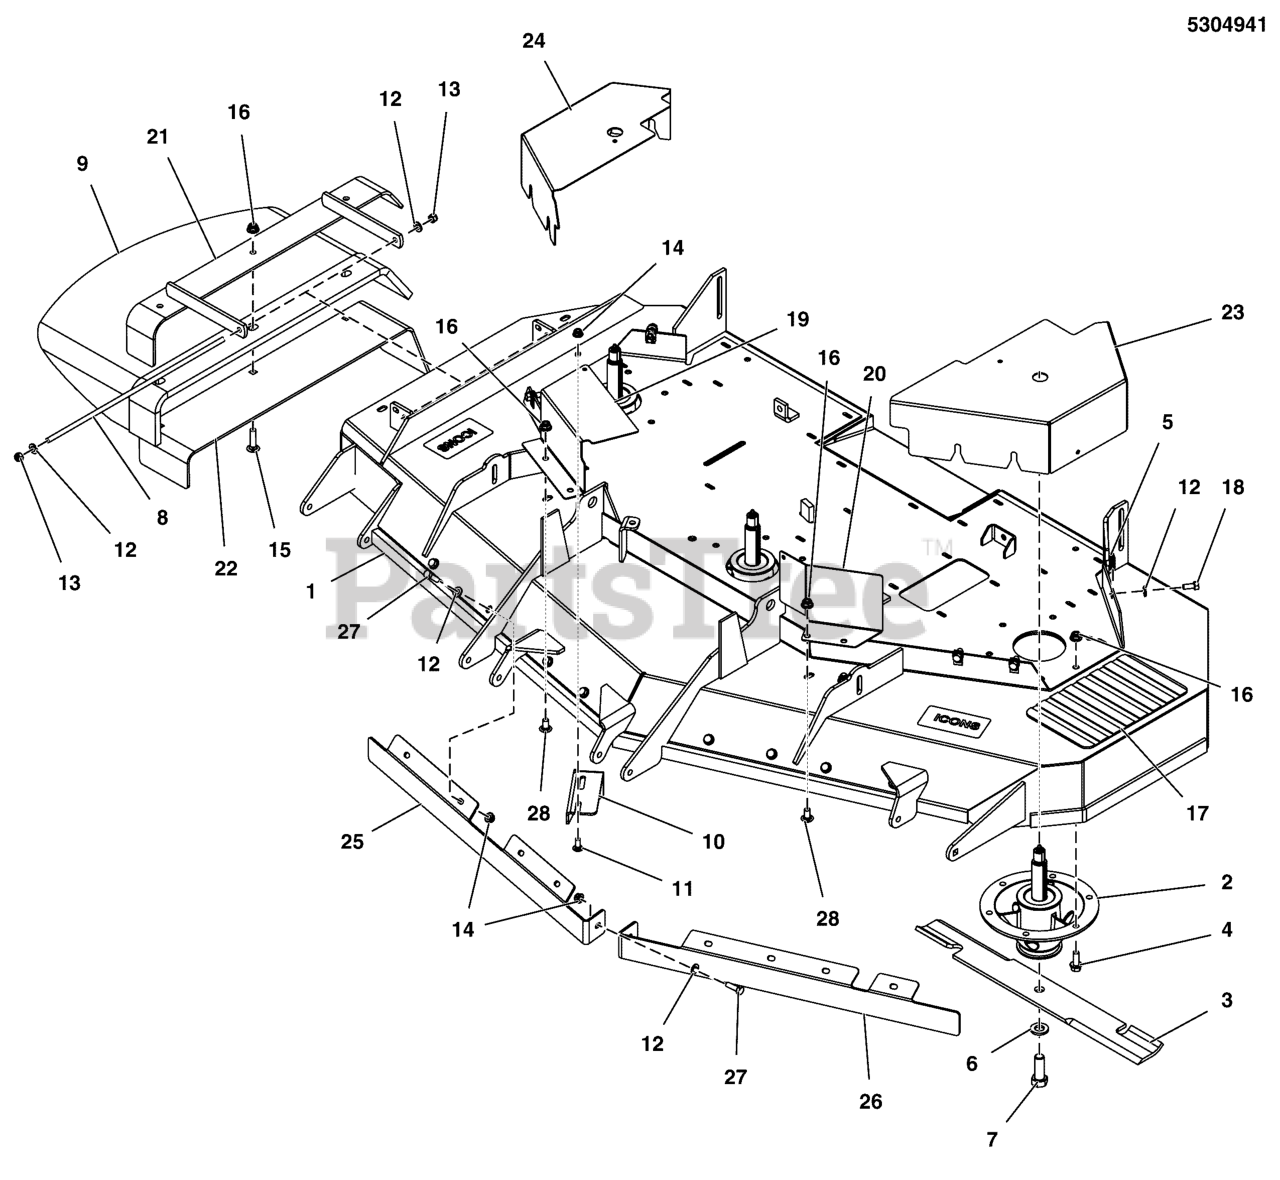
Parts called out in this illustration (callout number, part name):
1	DECK SHELL W/DECALS, F210Z-EXP (5416303B)
1	DECK SHELL W/DECALS, F210ZEXP (5417027B)
2	SPINDLE ASSM, CAST IRON 8.0-6 BOLT, LS
3	BLADE SET, 61 DECK (3)
4	BOLT, 3/8-16 X 1, FLANGE, GD 5, CZ
5	BODY CLIP, 5/16-18-7GA MATERIAL
6	WASHER, BLADE BOLT, 9/16" F436, CZ
7	BOLT, 5/8-11 X 1-3/4 GD8
8	ROD, MOUNT, CHUTE, 61, CZ
9	CHUTE, RUBBER DISCHARGE (5104442)
10	PLATE, DEFLECTOR - BLK
11	BOLT, 5/16-18 X 3/4, CARRIAGE, GD5, CZ
12	WASHER, 5/16" SAE
13	NUT, 5/16-24 HEX NYLON LOCK
14	NUT, 5/16-18 HEX NYLOCK FLANGE NUT
15	BOLT, 3/8-16 X 1-1/2, CARRIAGE, GD5, CZ
16	NUT, 3/8 - 16 HEX NYLOCK FLANGE
17	SAFETY WALK, 9.75 X 6.00
18	BOLT, 5/16-18 X 3/4 GD5
19	GUARD, PULLEY, RH, 61 CE - RED
20	GUARD, PULLEY, LH, 61 CE - RED
21	WELD, CHUTE MOUNT, CE - BLK
22	SUPPORT, DISCHARGE CHUTE, CE - BLK
23	GUARD, CUTTER DECK.LH, 61CE - RED
24	GUARD, CUTTER DECK.RH, 61CE - RED
25	BAFFLE, BLOWOUT, 61 ICD, RH - RED
26	BAFFLE, BLOWOUT, 61 ICD, LH - RED
27	BOLT, 5/16-18 X 1" GRD5 YZ
28	BOLT,3/8-16X.75,GR5,CARRIAGE,ZC/CL
